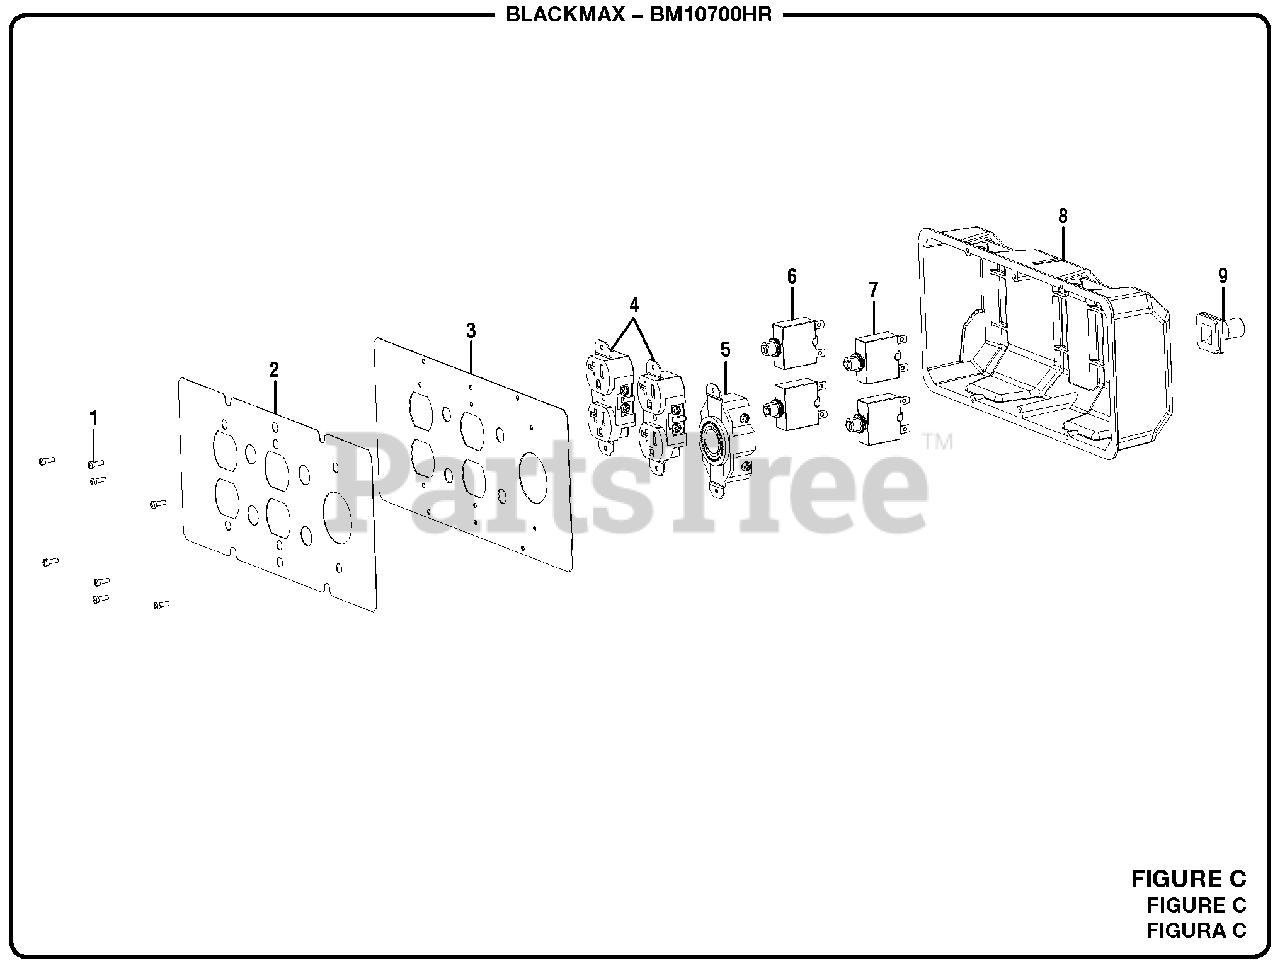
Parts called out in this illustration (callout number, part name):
1	Screw (6-20 x 3/8 in)
2	Label (Power Outlet)
3	Front Panel
4	120 Volt Duplex Receptacle
5	Twist Lock Receptacle (120/240 Volt, 30 Amp, L14-30R)
6	Circuit Breaker (20 Amp, 125 Volt)
7	Circuit Breaker (30 Amp)
8	Control Box (Back Panel)
9	Rubber Sleeve
